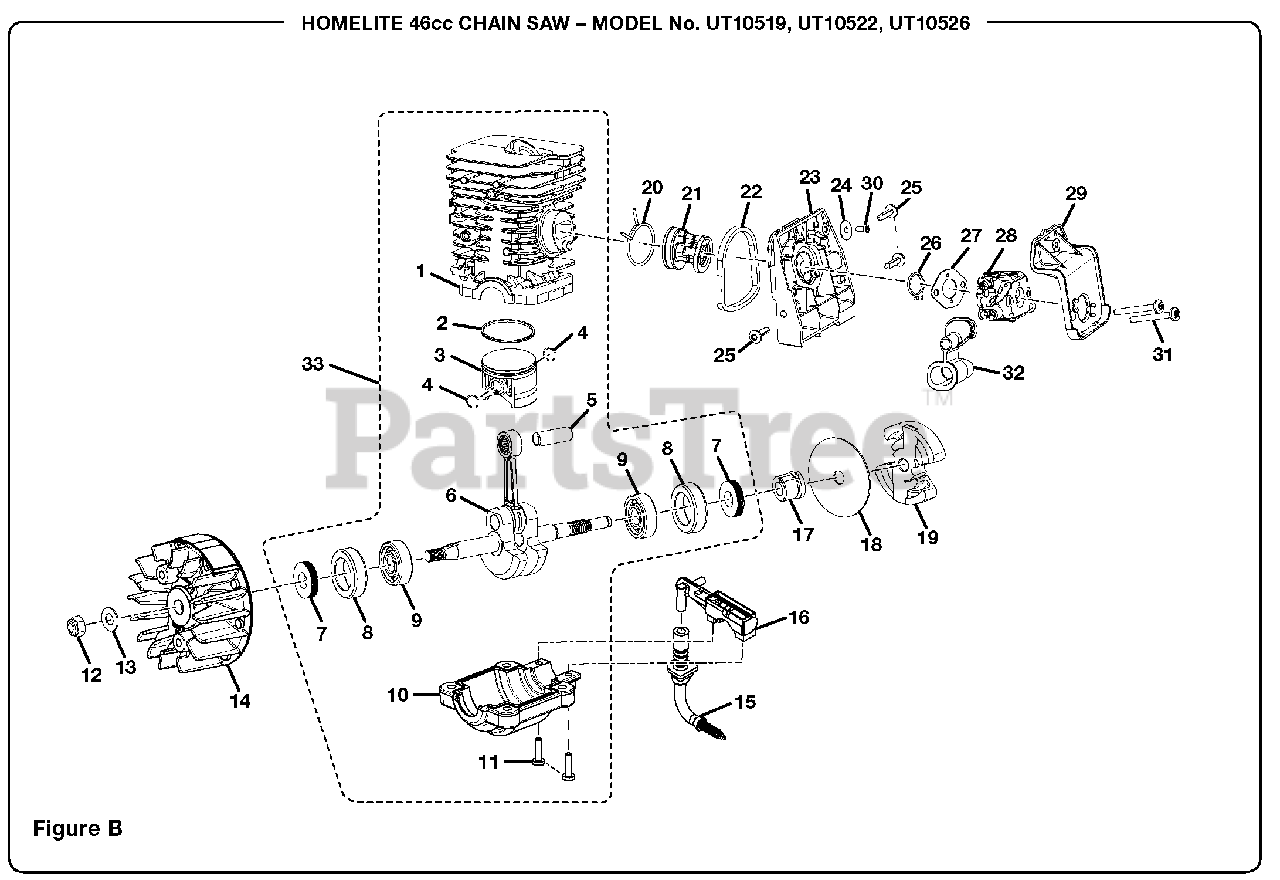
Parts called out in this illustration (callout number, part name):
2	Piston Ring
4	Retaining Ring
5	Piston Pin
6	Crankshaft Assembly
7	Shaft Seal
8	Bearing Case
9	Ball Bearing
10	Crankcase
11	Screw (8-32 x 5/8 in.)
12	Hex Nut (5/16-24)
13	Washer
14	Flywheel Assembly
15	Oil Intake Tube Assembly
16	Oil Pump Assembly
17	Left Hand Worm
18	Thrust Washer
19	Clutch Assembly
20	Wire Clamp
21	Intake Boot
22	Carburetor Adaptor Seal
23	Carburetor Adapter
24	Washer
25	Screw (10-14 x 3/4 in.)
26	Carburetor Plate
27	Carburetor Gasket
28	Carburetor Assembly (Zama)
29	Air Filter Base
30	Screw (8-16 x 5/16 in.)
31	Screw (10-32 x 1 3/4 in.)
32	Grommet
33	Short Block Assembly (Inc. Key Nos. 1-11)
